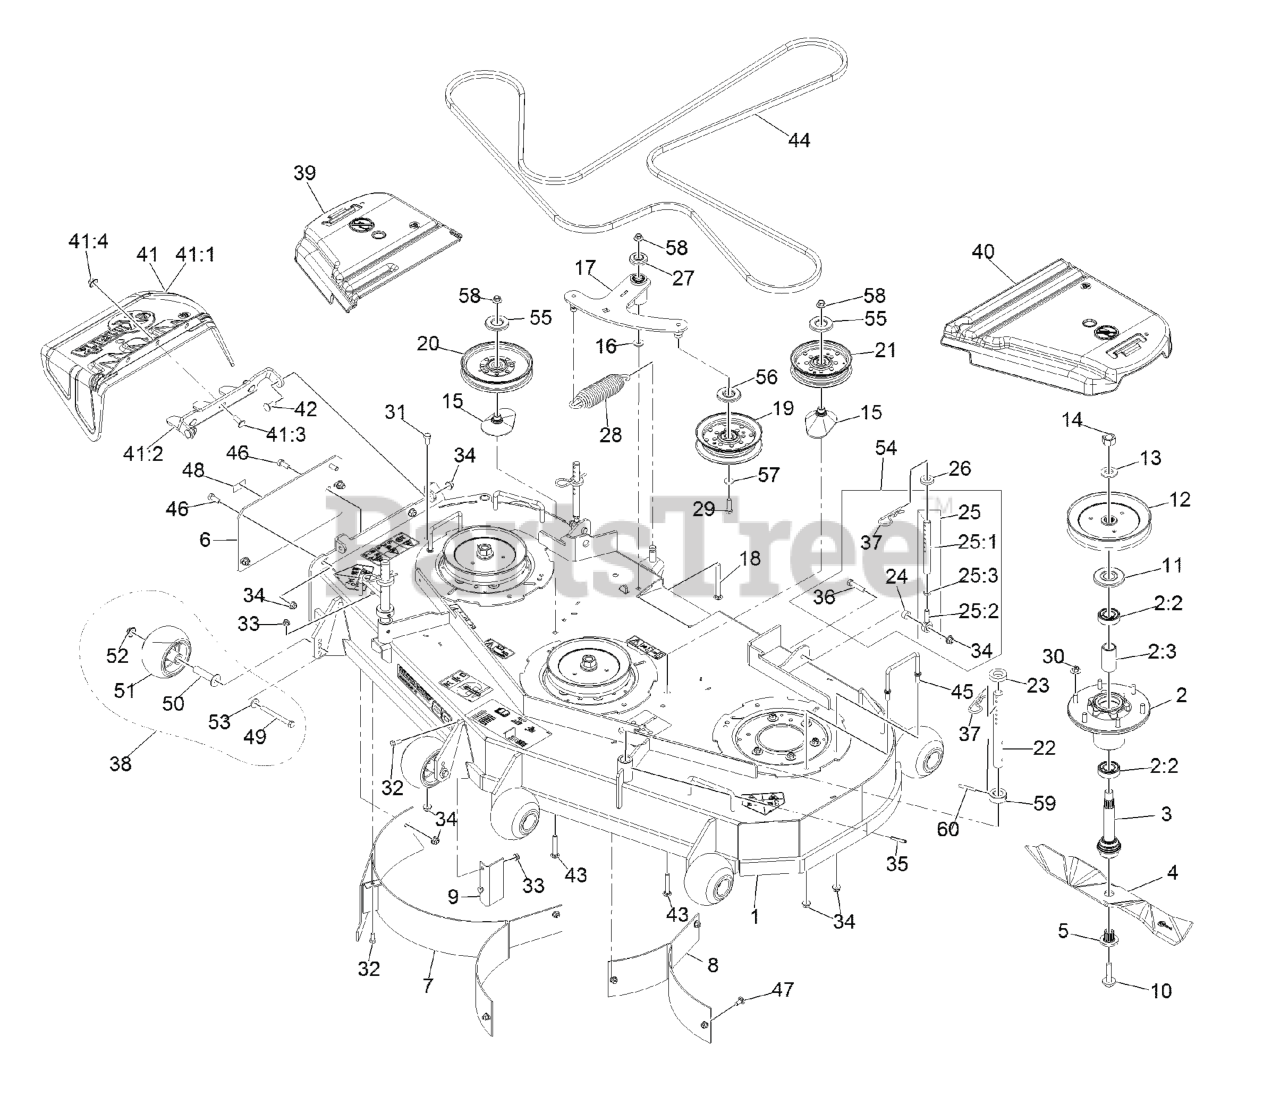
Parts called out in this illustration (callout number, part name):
1	ASM, DECK W/ DECALS, 60"
2	ASM-CUTTER HSG WITH BEARINGS
2:2	BEARING-BALL
2:3	SPACER-BEARING
3	ASM-SPINDLE AND SEAL
4	Blade-Extreme 2, 20.50"
5	BUSHING,SPLINED
6	PLATE-MULCH COVER, 604
7	BAFFLE WLD RH MULCH
8	XREF 1-632948-03 (EXMARK)
9	BAFFLE,BLOCKER MK604
10	SCREW,SEMS 1/2-20 X 2.19
11	GUARD,BEARING TOP .989
12	SHEAVE,BLADE DRIVE 7.25
14	NUT-HEX
15	SPACER-PULLEY
16	WASHER-FLAT
17	ASM, DECK IDLER
18	SCREW-CARR
19	IDLER-PULLEY, FLAT
20	IDLER-PULLEY
21	PULLEY-IDLER, FLAT
22	Rod, Deck Support
23	SPACER-DECK SUPPORT
25:1	LINK,SUPPORT
25:2	BALLJOINT
25:3	NUT-HJ
27	GUARD-TOP
28	SPRING-EXTENSION
29	SCREW-HH
30	Nut-Nyloc 3/8-16 Flg
31	SCREW-HH
32	SCREW-HH
33	NUT-HF, NI
34	NUT-HF, NI
36	SCREW-HH
37	PIN,HAIR COTTER
38	KIT, ANTI-SCALP ROLLER
39	COVER-BELT, RH
40	COVER-BELT, LH
41	ASM,DISCHARGE CHUTE
41:1	CHUTE,DISCHARGE
41:2	BRACKET,DISCHARGE CHUTE
41:3	SCREW-CARR
41:4	Nut-Nyloc 3/8-16 Flg
42	SCREW-CARR
43	BOLT-CARR, SHORT NECK
44	BELT, DECK DRIVE
45	WIREFORM-COVER
46	SCREW-HH
47	BOLT-CARR
48	Decal-Patent Ttco.Com
49	SCREW-HH 3/8-16 X 3 3/4 GR 8
50	AXLE, ROLLER
51	ROLLER-SCALP, ANTI
52	Nut-Nyloc 3/8-16 Flg
53	WASHER-BELLEVILLE
54	KIT,SUPPORT LINK W/PIN
55	SHIELD-DUST
56	SHIELD-GUARD, DUST
59	Collar, Deck Height Pin
60	PIN-ROLL
